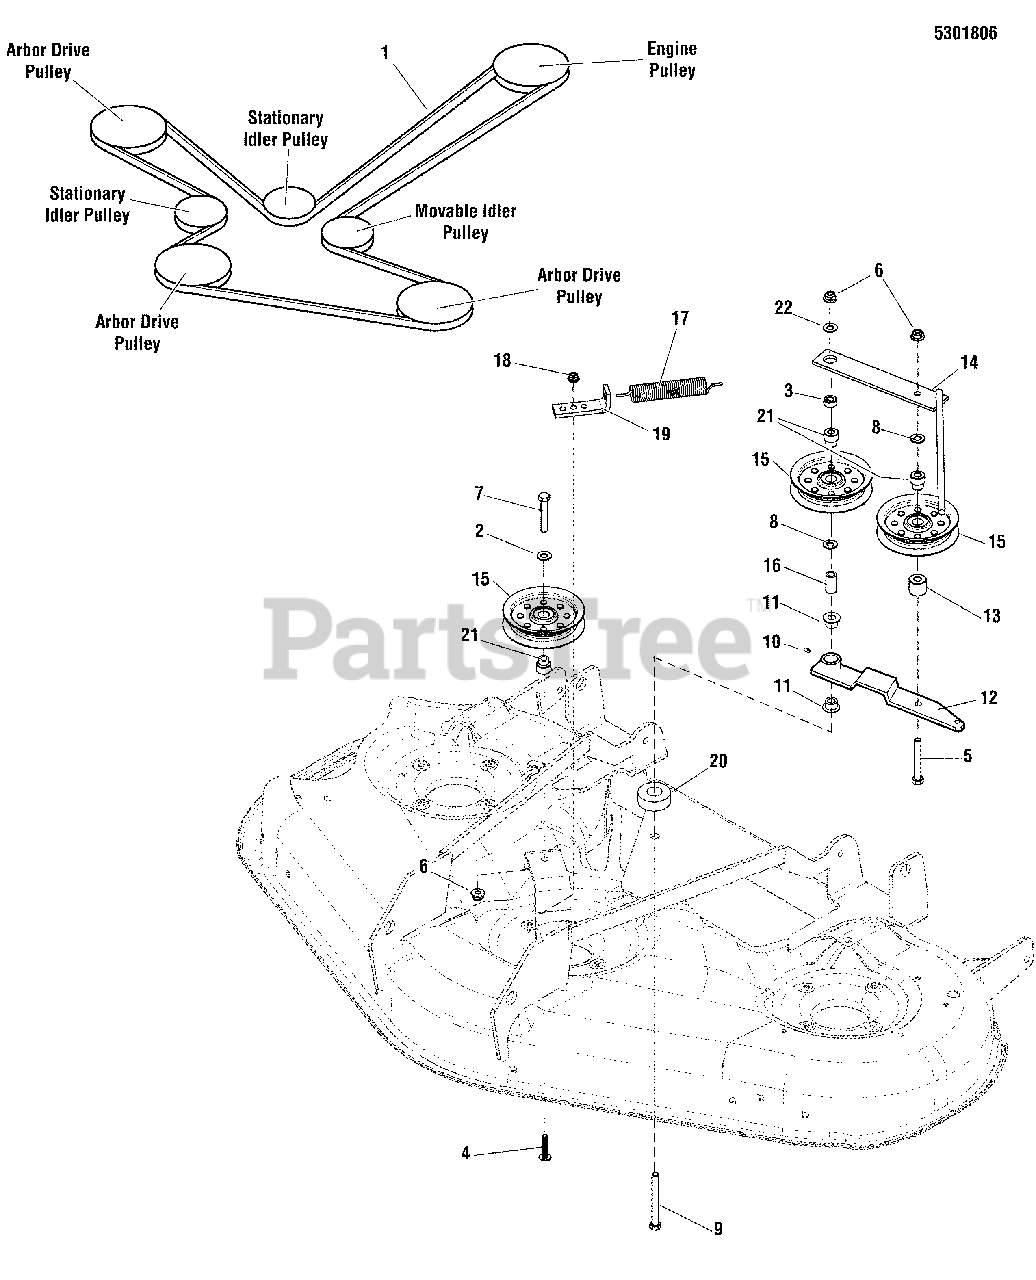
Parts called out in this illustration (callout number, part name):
1	BELT, A-SEC, 145.5 EL, LG ARAMID, WRAP
2	WASHER, 3/8 USS
3	SPACER, .39 X .75 X .38
4	CAPSCREW, Hex Washer Head Taptite, 5/16-18X1.000BLK
5	BOLT, 3/8-16 X 2-3/4" GD5 CZ
6	NUT, 3/8-16 HEX NYLOCK FLANGE
7	BOLT, 3/8-16 X 2, GD5, CZ
8	WASHER, 3/8 SAE
9	BOLT, 3/8-16 X 4" GD5 CZ
10	GREASE FITTING, 1/4-28 STRAIGHT
11	BUSHING, 0.628IDX0.751ODX0.400LG PWDR MTL
12	WELD, DECK, IDLER ARM - RED
13	SPACER, .39 X 1.00 X .88
14	WELD, MOUNT, IDLER TENSION - RED
15	PULLEY, IDLER, 4.06OD, .669ID, .75W STL
16	SPACER, 0.39 IDX0.625ODX1.15 LG CASE HARD
17	SPRING, EXTENSION, 1.00
18	NUT, HEX FLANGE 5/16-18, WHIZ LK SM, YZ
19	BRACKET, SPRING ANCHOR - RED
20	SPACER, .39 X 1.75 X .63, YZ
21	SPACER, HYDRO PULLEY
22	WASHER, 3/8 FENDER
